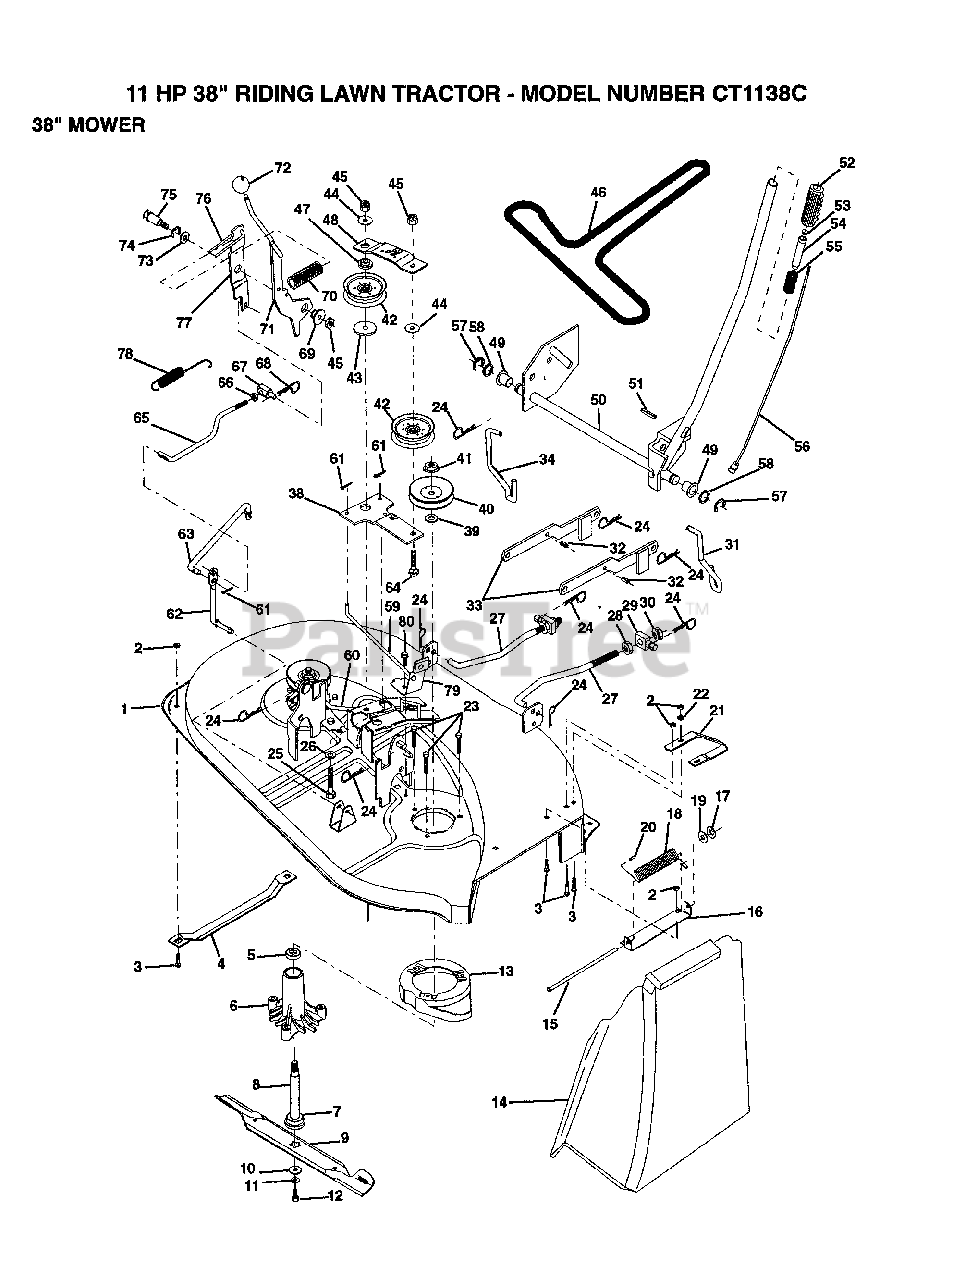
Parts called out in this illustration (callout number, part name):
3	BOLT
4	RUNNER-LH M
5	BEARING
6	HSG ASM MANDREL
7	BEARING.BALL
10	WASHER BLADE
12	BLADE BOLT
14	DEFLECTOR-SHLD T
15	ROD-HINGE T
17	NUT PUSH M
19	WASHER
20	CAP-SLEEVE LT
21	RUNNER RH
22	WASHER M
25	BOLT
26	WASHER GT
27	LINK.FRONT
28	NUT
29	TRUNION
30	NUT.LK.W/WSH.1/2.
31	LIFT LINK RH
32	"PIN,SPRING"
33	SUSP ARM ASM REAR
34	LINK LIFT LH
38	IDLER ARM ASSY
39	WASHER
42	FLAT IDLER PULLEY
43	SPACER RETAINER
44	WASHER GT
46	BELT-V.88.12.MW
47	RETAINER SPACER
48	IDLER ARM STIFF
49	NYLON BEARING
51	PIN-GROOVE LT
52	GRIP
58	WASHER
59	BRAKE ROD RH
60	BRAKE ROD LH
62	PIVOT ROD
63	CLUTCH ROD SECOND
64	BOLT
66	NUT
67	TRUNION
68	RETAINER M
69	BUSHING
71	CLUTCH ARM PRI AS
72	KNOB T(3/8 HOLE)
73	WASHER
74	RING
75	SHOULDER BOLT
76	SPRING KEEPER
77	CLUTCH ARM SECOND
78	RETURN SPRING
79	BRAKE ASM
80	SCREW
